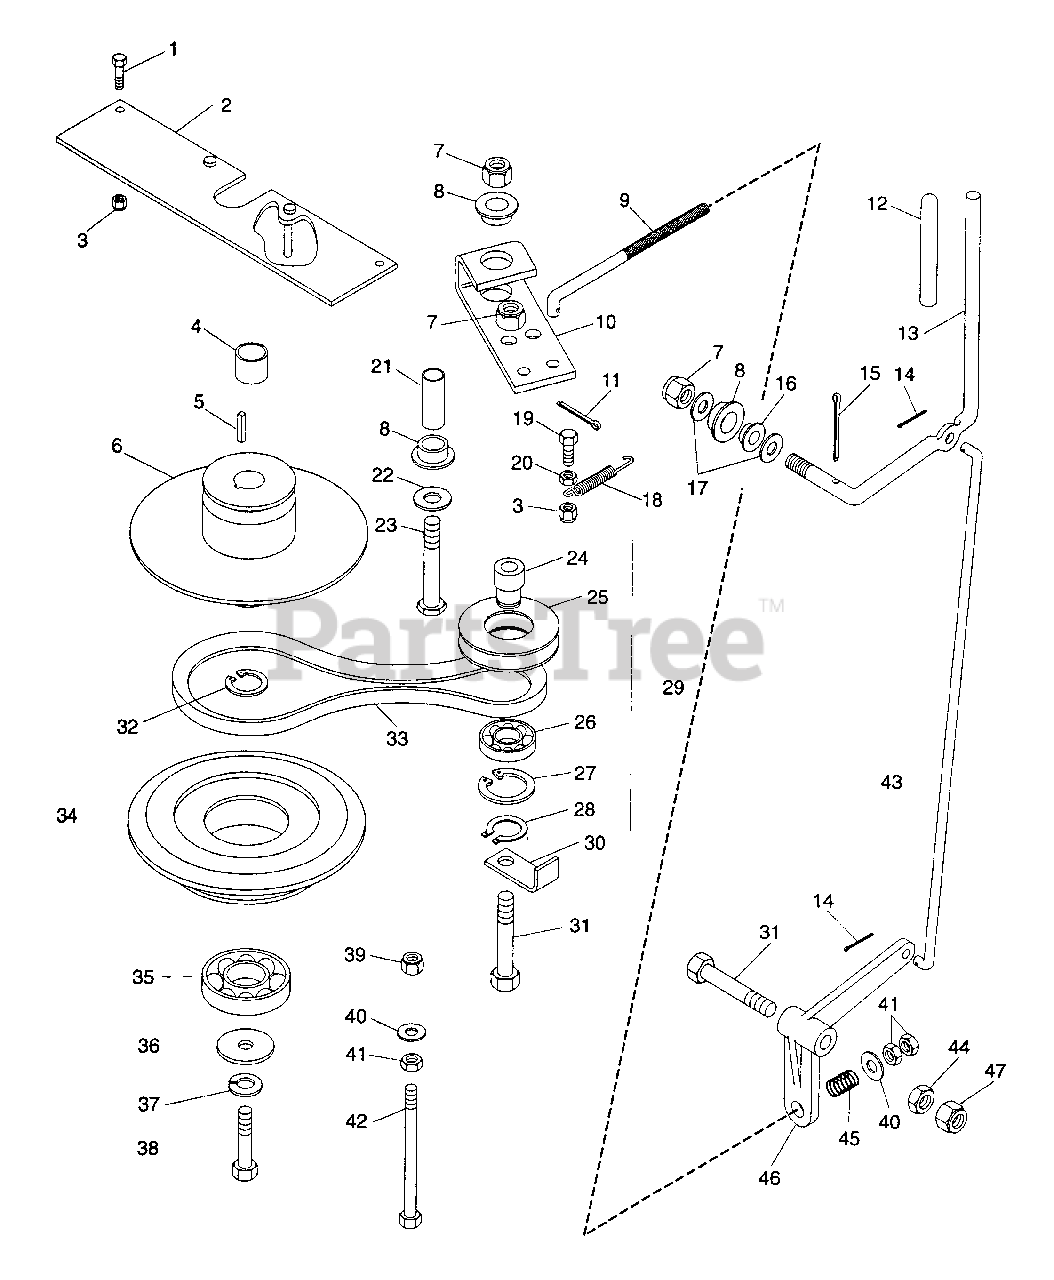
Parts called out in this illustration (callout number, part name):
1	Bolt-Hex .31-18 x .75 Grade 5
2	Weldment, Belt Guide
3	Nut-Locking-Nylon .312-18 Grade 2
4	Spacer, Manual Start
5	Key-Square .248 x 1.25 x .248
6	Hub, PTO & Drive Clutch
7	Nut-Locking-Nylon .50-13 Grade 5
8	Bushing-Flange .762 x 1.0 x .580 x 1.48
9	Rod, PTO Clutch Actuating
10	Arm, Idler Pivot
11	Pin-Cotter .12 x .75
12	Grip, PTO Lever
13	Lever, PTO Actuating
14	Pin-Cotter .09 x .75
15	Pin-Cotter .188 x 1.625
16	Bushing-Flange .515 x .750 x .745 x 1.00
17	Washer-Flat-Steel .531 x .750 x .100
18	Spring-Tension .061 x .50 x 3.5
19	Bolt-Hex.31-18 x 1.00 Grade 5
20	Nut-Hex .312-18 Grade 2
21	Bushing, Steel .560 x .745 x 2.04
22	Washer-Flat-Steel .531 x 1.062 x .095
23	Bolt, Hex 1/2-13 x 2.75
24	Bushing, Flange .515 x .787 x 1.41
25	Sheave, Idler
26	Bearing-Ball 1.85 x .787 x .55
27	Ring-Retaining-Internal 2.054 x .062
28	Ring-Retaining-Truarc
29	Assembly, Idler Sheave
30	Guard, Belt
31	Bolt-Hex .50-13 x 2.50 Grade 5
32	Ring-Retaining
33	V-Belt A-Section
34	Sheave, Mower Clutch
35	Bearing-Ball 1.57 x 3.15 x .71
36	Washer-Special .469 x 2.000 x .250
37	Washer-Lock .44 Reg.
38	Bolt-Hex 10MM x 1.5 x 60MM
38	Bolt-Hex .44-20 x 2.50
39	Nut-Locking-Nylon .375-16 Grade 2
40	Washer-Flat-Steel .406 x .812 x .065
41	Nut-Hex .375-16 Grade 2
42	Bolt-Hex .38-16 x 4.00
43	Rod, PTO Control
44	Nut-Jam .50-13 Grade 2
45	Spring-Compression .125 x .78 x 1.00
46	Lever, PTO Clutch
47	Nut-Locking .50-13
